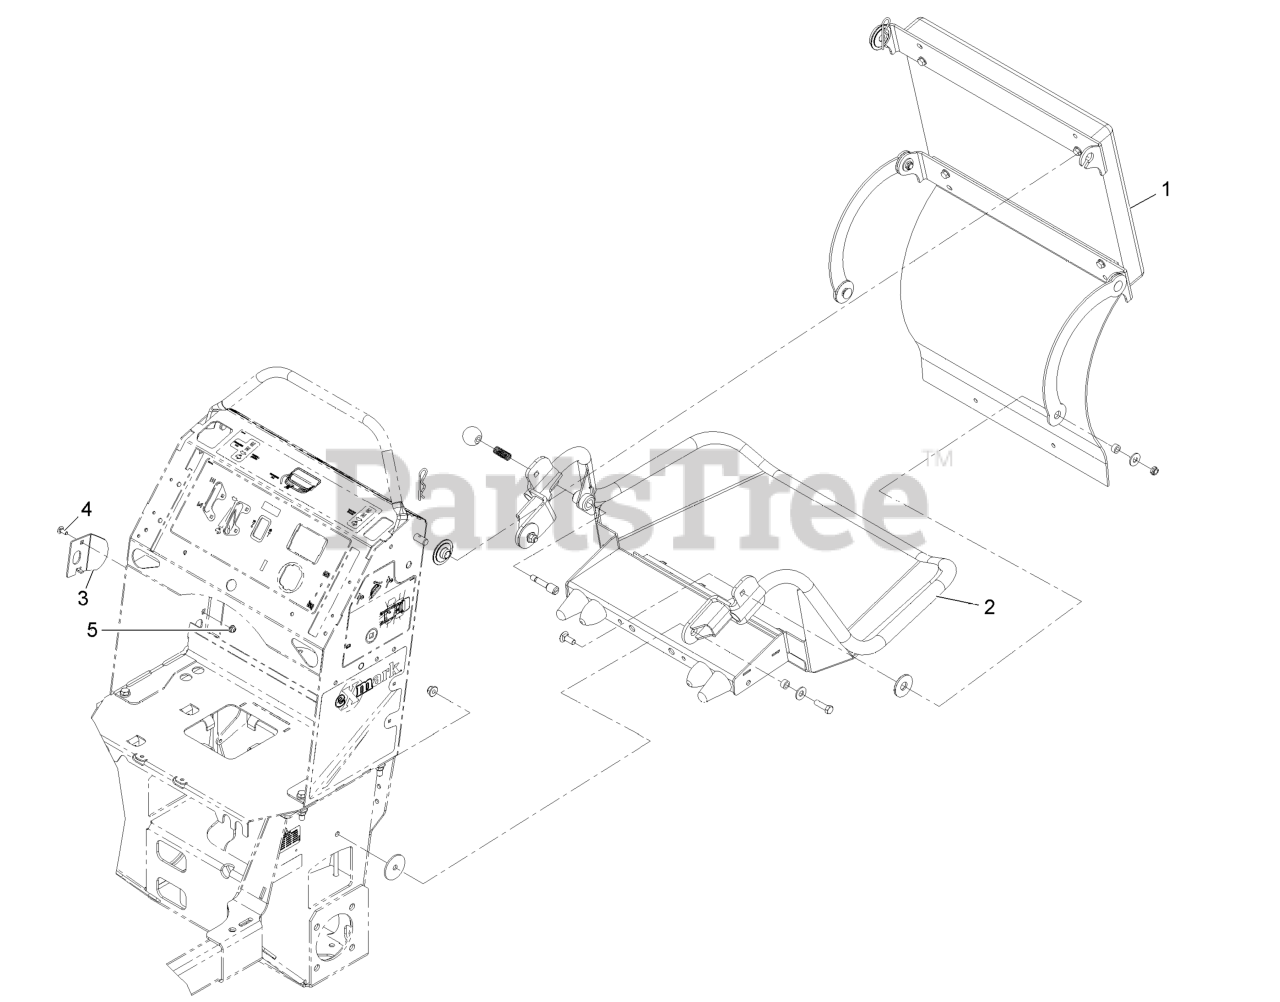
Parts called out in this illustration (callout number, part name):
2	PLATFORM ASM
3	PLATE-STRIKER
4	SCREW-CARR
